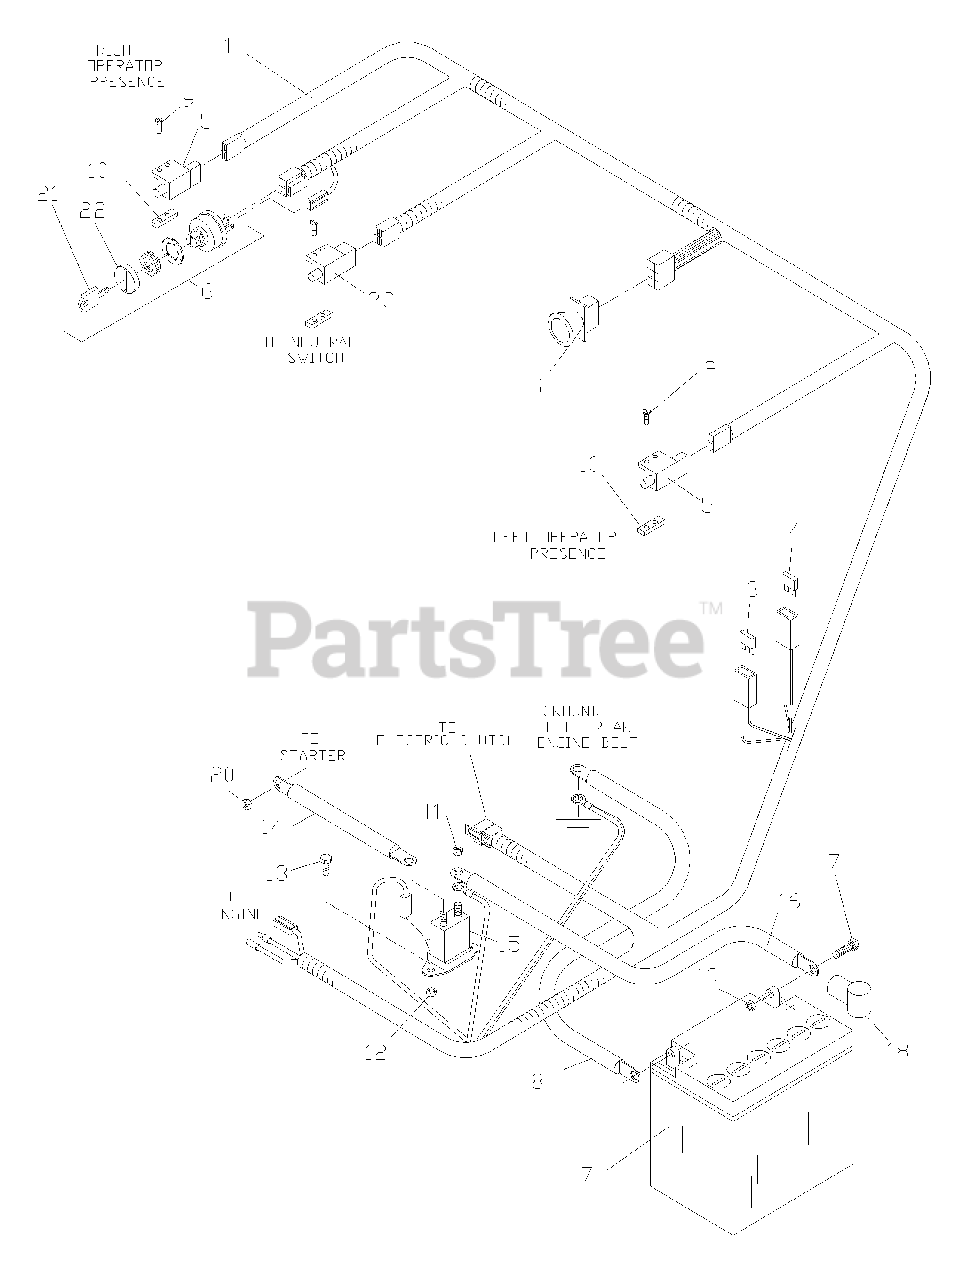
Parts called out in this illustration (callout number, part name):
1	WIRING HARNESS
2	CLUTCH SWITCH
3	FUSE 20 AMP
4	FUSE 7.5 AMP
5	SWITCH N. C.
6	IGNITION SWITCH
6	NUT, SWITCH
7	BATTERY
8	NEG. CABLE
9	SCREW #10-24
10	TAPPED PLATE
11	NUT 1/4
12	NUT 1/4 LOCK
13	HCS 1/4 X .625
14	POS. CABLE
16	POS. CABLE LONG
17	HCS 5/16 X .750
19	NUT 5/16 CTR. LOCK
20	NUT 1/4 NYLOC
23	2 POLE SWITCH
